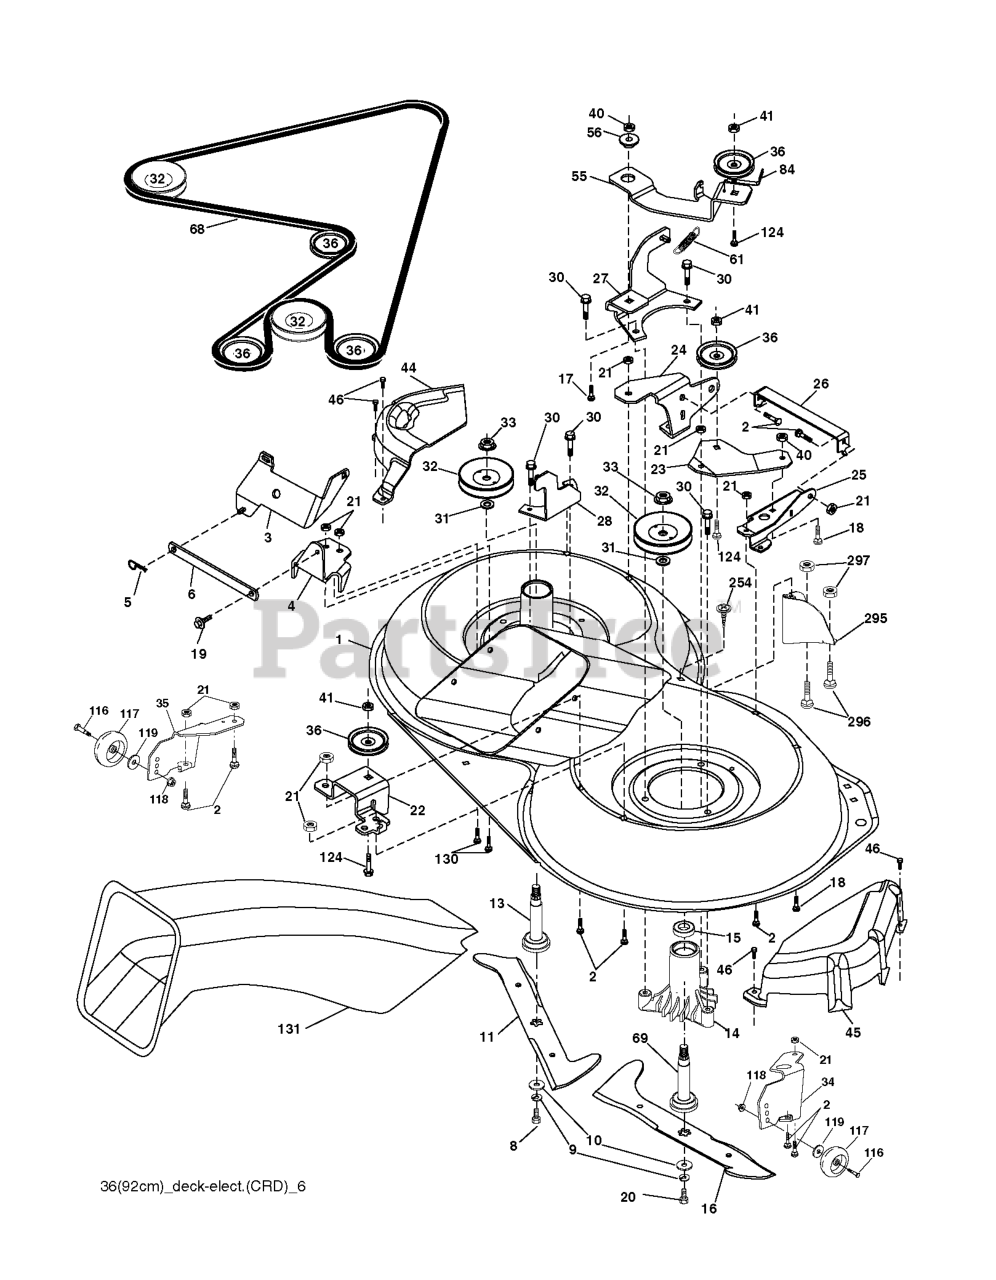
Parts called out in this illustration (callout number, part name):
1	FRAME MS 668
2	BOLT 3/8-16X1-1/8
3	COVER COVER.FRAME MS668 ORANGE
4	BRACKET.SHIFTER.BZP
5	SCREW.HEX HEAD W/COLLAR 1/4-20
6	WIREFORM.SUPPORT.CABLE
7	BOLT.HEX.HD.WASHER.5/16-18X.75
8	SCREW HEX_SERR_HD_5_16-18X1.0
9	SCREW.HEX HEAD W/COLLAR 1/4-20
